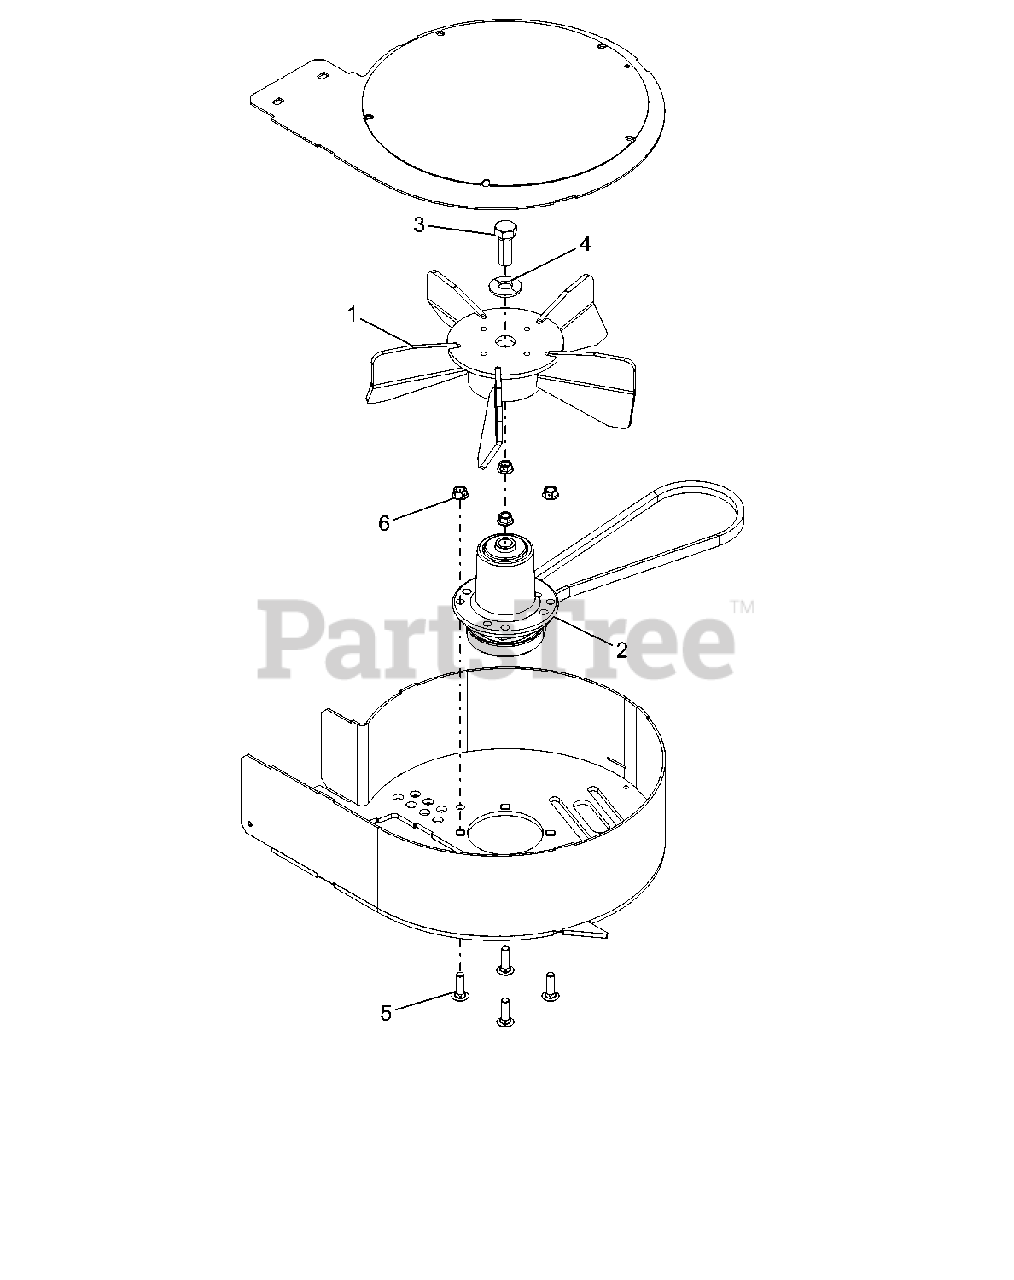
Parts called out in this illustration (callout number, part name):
1	WLDMT, IMPELLER FAN
2	ASM, SPINDLE BLOWER (SERVICE)
3	BLT, HEX .62-18X1.75 GR8 YWZC
4	WSHR, BLVL .63X1.625X.14
5	BLT-RDHDSQNK .38-16X1.25 G5 YWZC
6	NUT, LK-CTR-FLG .38-16 YWZC
